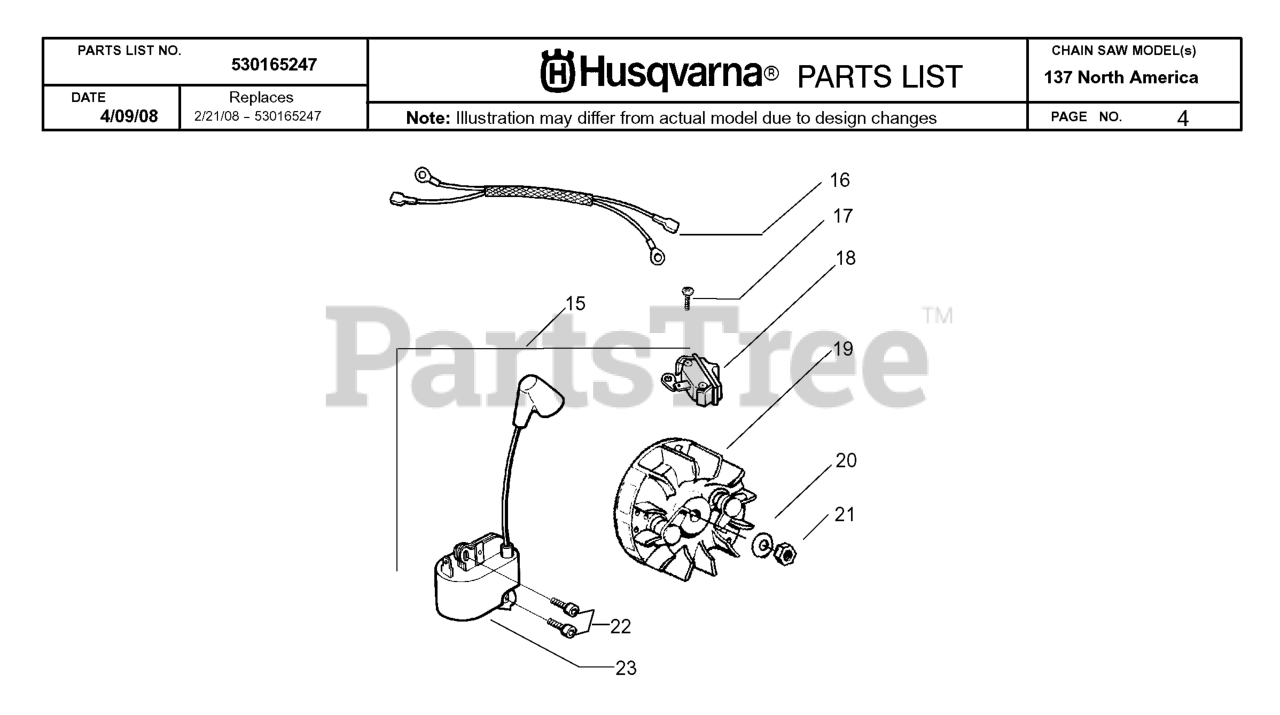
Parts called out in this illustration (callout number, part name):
15	KIT EPS IGNITION
16	LEAD WIRE ASSY
18	SWITCH ON/OFF
19	FLYWHEEL ASSY
20	WASHER-FLYWHEEL
21	NUT-FLYWHEEL
23	IGNITION MODULE
